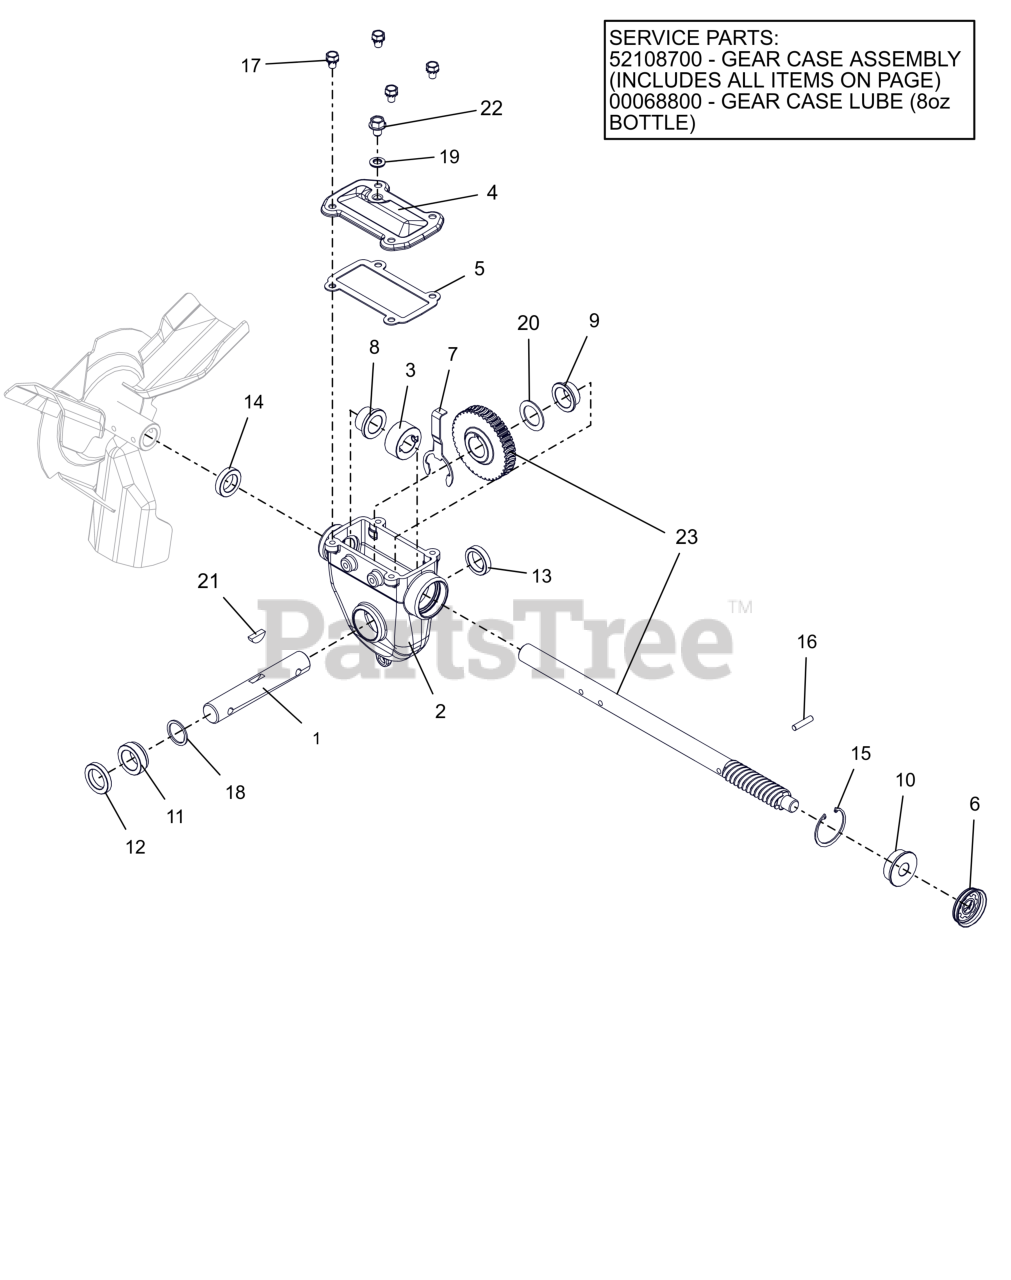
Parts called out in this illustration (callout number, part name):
1	RAKE SHAFT, SHORT-COMMON
2	GEARCASE, LARGE MACHINED
2	KIT, SERVICE - DLX GEAR CASE
2	ARIENS L3 LUBE, 8 OZ BOTTLE
3	THRUST COLLAR, .875"ID SLIPFIT
4	COVER, TOP - LARGE IRON
5	GASKET, TOP - LARGE GEARCASE
6	COVER, GEAR CASE 1.75"
7	BUSHING RETAINER, LARGE
8	BSHG-FLG .879X1.128X.75X1.45
9	BSHG-FLG 1.006X1.128X.555X1.45
10	BSHG-FLG .628X1.503X.58X1.725
11	BSHG-FLG LARGE, RIGHT
12	SEAL-OIL .999X1.500X.250 TBC29
13	SEAL-OIL .999X1.375X.312 TBC29
14	SEAL-OIL .873X1.375X.312 TBC29
15	RG-RTNG-INT 1.750X.062
16	PIN-STR .250X1.12 6150
17	BLT, SEMS .31-18X.50 G5 ZCC
18	WSHR, FLT 1.010X1.250X.068 ZCC
19	WSHR-BND-SEAL .38X.75X.11 GALV
20	WSHR, FLT 1.010X1.505X.062 ZCC
21	KEY-WDRF .25X.875 HRD #A
22	SCR,TAP .38-15X.50 HWH ROLOK
23	KIT, SERVICE-WORM SHAFT & GEAR
